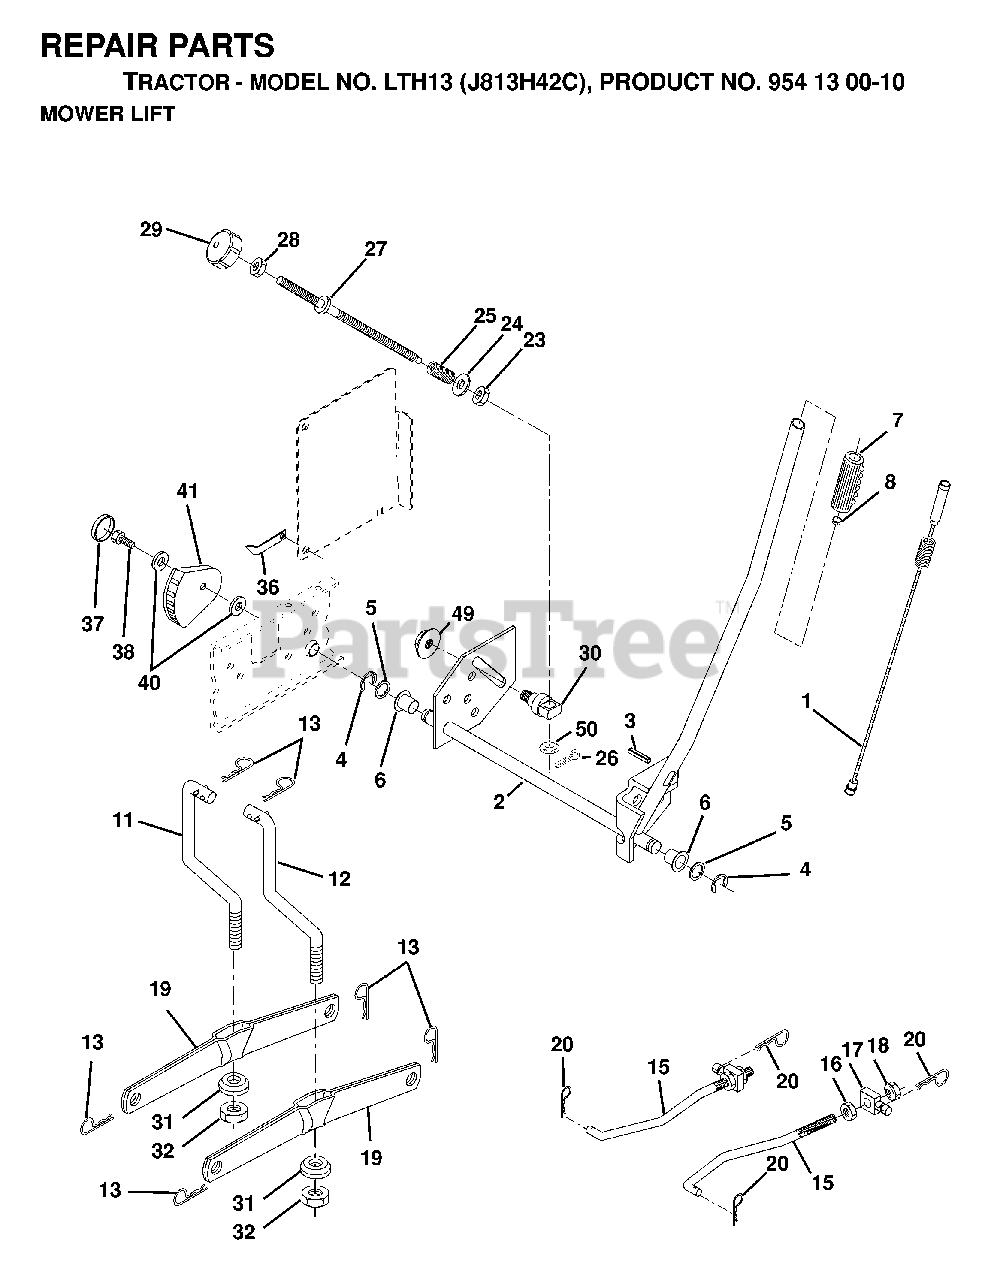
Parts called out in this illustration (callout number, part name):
1	WIRE ASM INNER W/ PLUNGER LT
2	SHAFT ASM R HANDLE
3	PIN GROOVE
4	RETAINING RING LT
6	BEARING.NYLON
7	GRIP HANDLE
8	PLUNGER BUT KIT
11	LINK LIFT LH
12	LINK LIFT RH
13	RETAINER-SPRNG RB
15	FRONT LINK
16	NUT
17	TRUNION
18	NUT LTV
19	ARM.REAR.SUSPENSION
20	SPRING RETAINER
25	SPRING**
26	COTTER PIN
27	ROD ADJ LIFT
28	NUT
29	KNOB INF 3/8-16
31	BEARING PIVOT
32	NUT CROWNLOCK 3/8-24
36	POINTER, HEIGHT INDICATOR
37	PLUG,HOLE
38	SCREW
41	IND. HEIGHT STLT
49	NUT
50	NUT PUSH M
